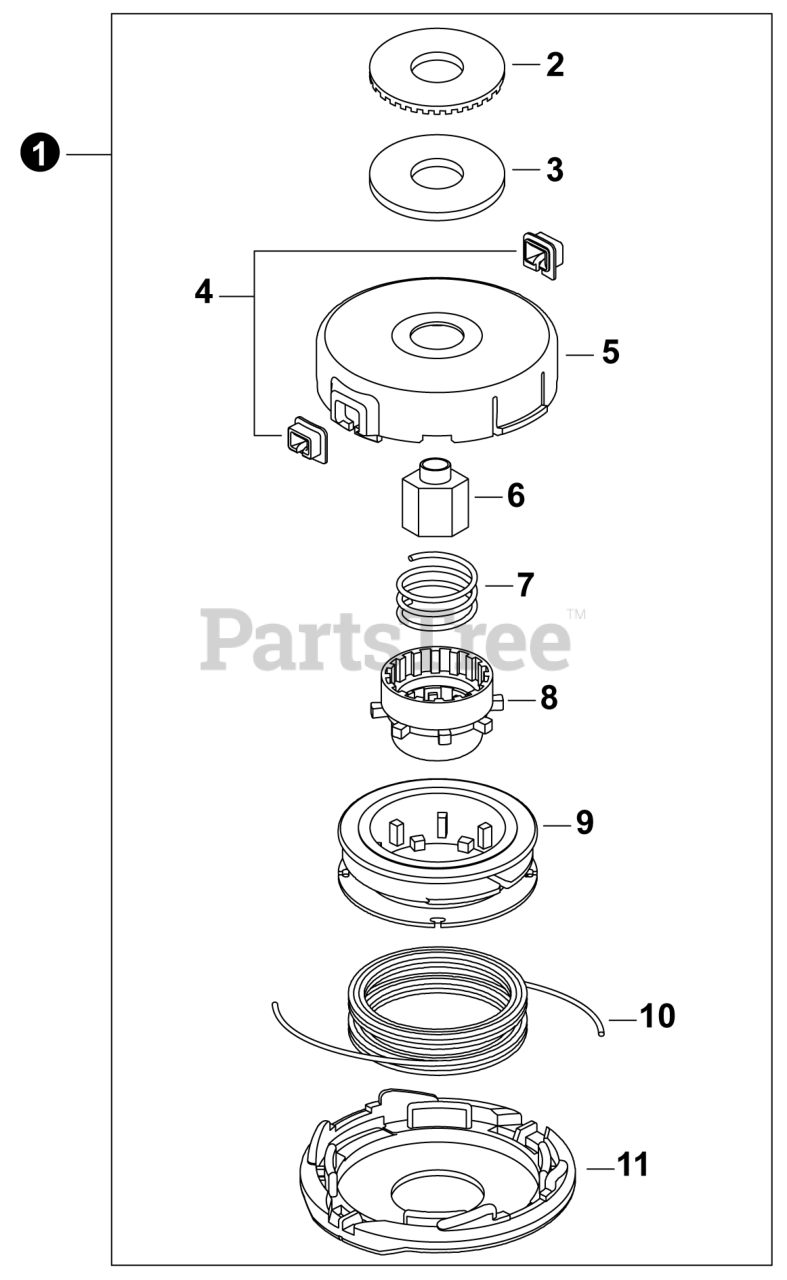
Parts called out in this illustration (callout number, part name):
1	TRIMMER HEAD DS-5 M10L
2	WASHER
3	SPACER
5	HOUSING, SPOOL
8	KNOB, TAP
10	CORD, NYLON
